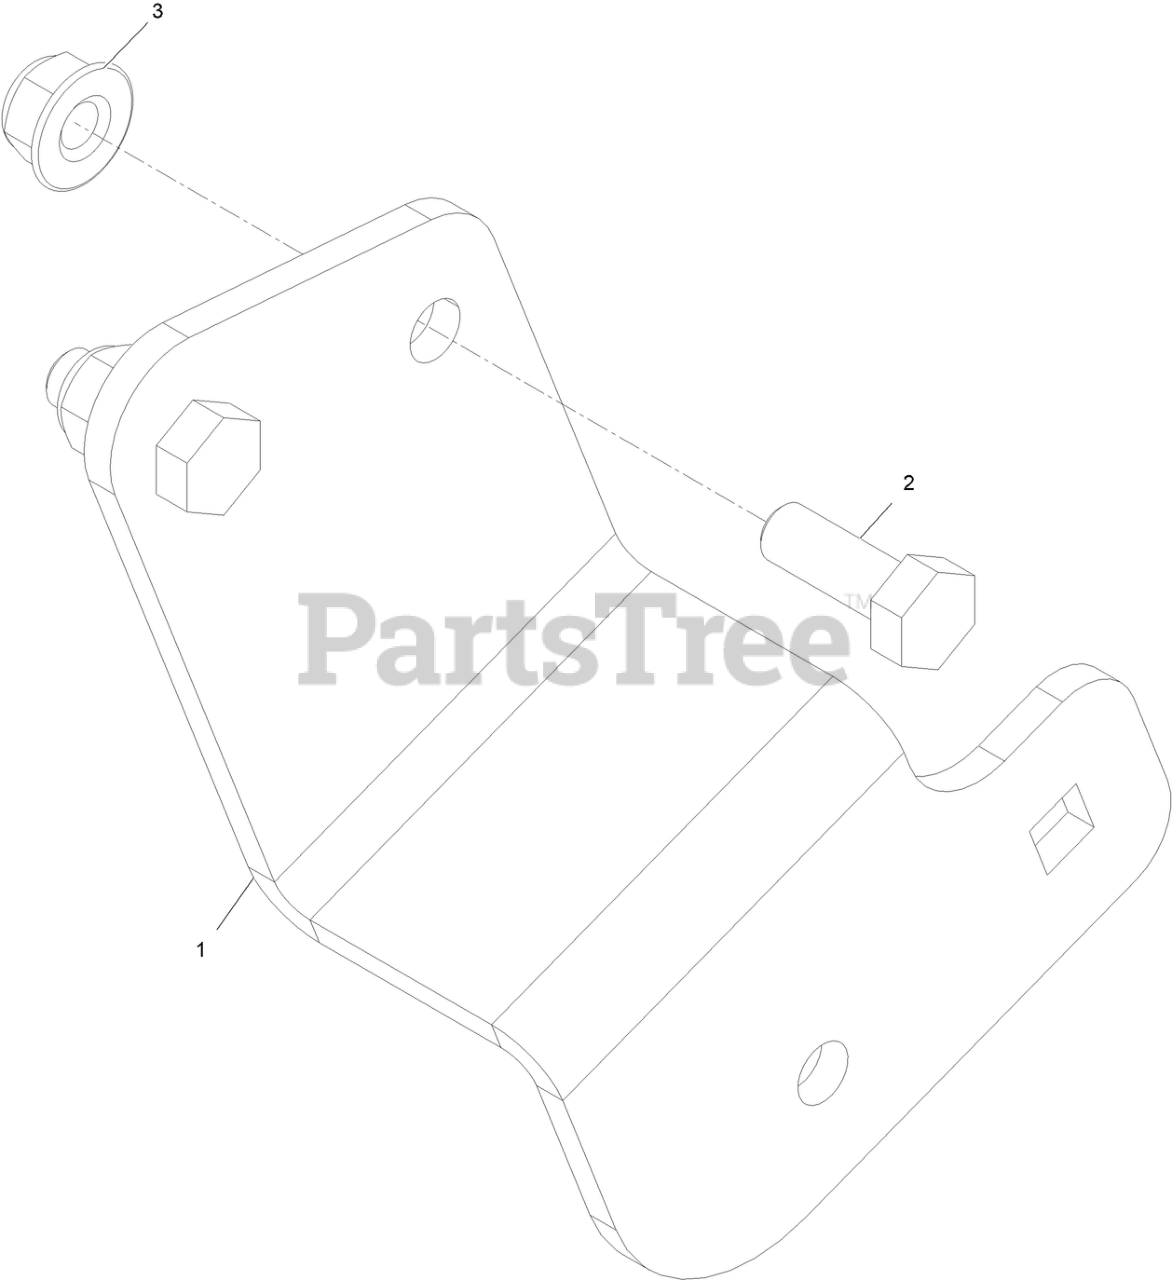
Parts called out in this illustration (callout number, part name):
1	BRACKET-OCD MOUNT
2	SCREW-HH
3	NUT-HF, NI
